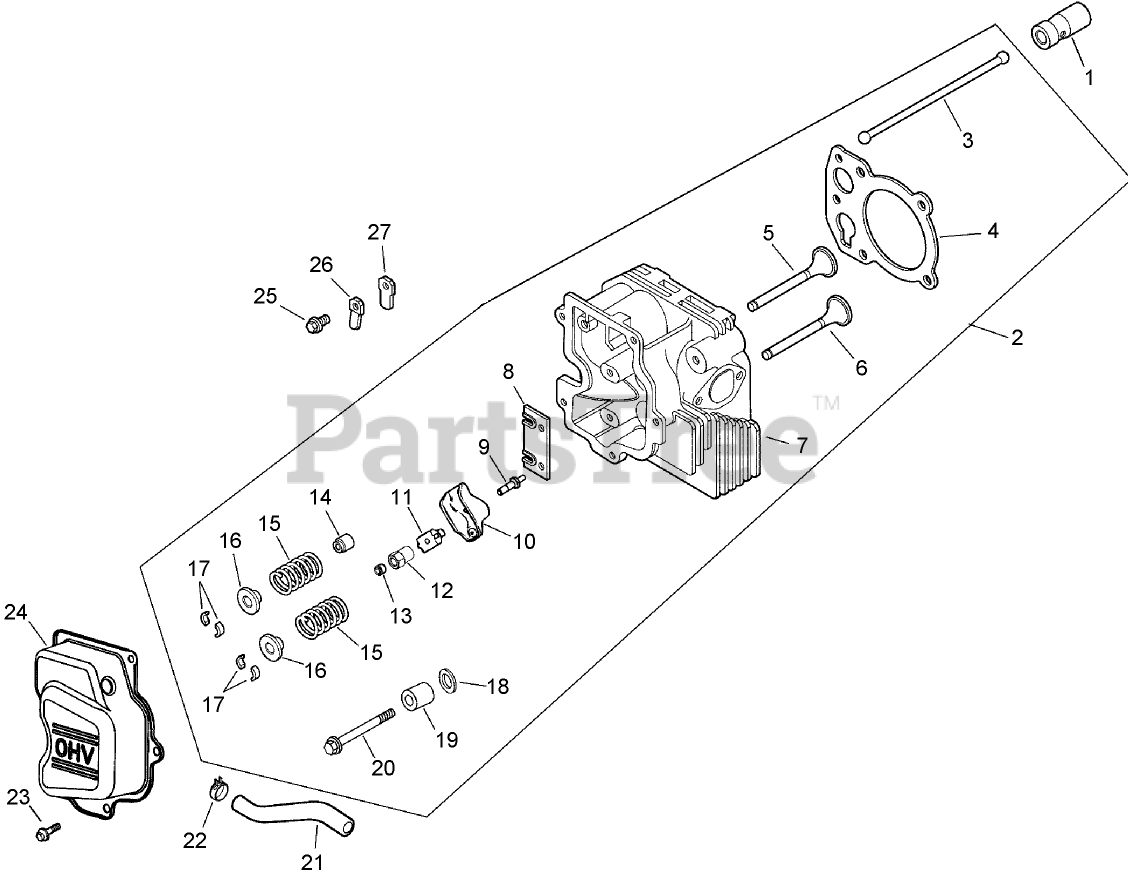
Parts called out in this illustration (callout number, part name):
1	Lifter-Valve
2	Cylinder Head Kit (Incl. Ref. #3-18, carburetor gasket 12 041 01-S (2), air cleaner base gasket 12 041 02-S, exhaust manifold gasket 12 041 03-S)
3	Rod-Push
4	Gasket-Head, Cylinder
5	Valve-Intake (STD)
6	Valve-Exhaust (STD)
7	Head-Cylinder
8	Plate-Guide
9	Stud-Rocker
10	ARM-ROCKER
11	Pivot-Arm, Rocker
12	Nut-Hex
13	Screw-Set
14	SEAL-STEM, VALVE
15	Spring-Valve
16	CAP-SPRING, VALVE
17	RETAINER KIT
18	Washer-Flat (1/2)
19	Spacer-Head Bolt (Exhaust Port)
20	Screw-Flange, Hex (M10x1.5x37)
21	Hose-Breather
22	CLAMP-HOSE, SPRING (1/2)
23	SCREW-FLANGE, THREAD FORMING (M6X1.0X16)
24	Cover-Valve
25	SCREW-HHFTF (M5X.80X10)
26	RETAINER-REED
27	REED-BREATHER
